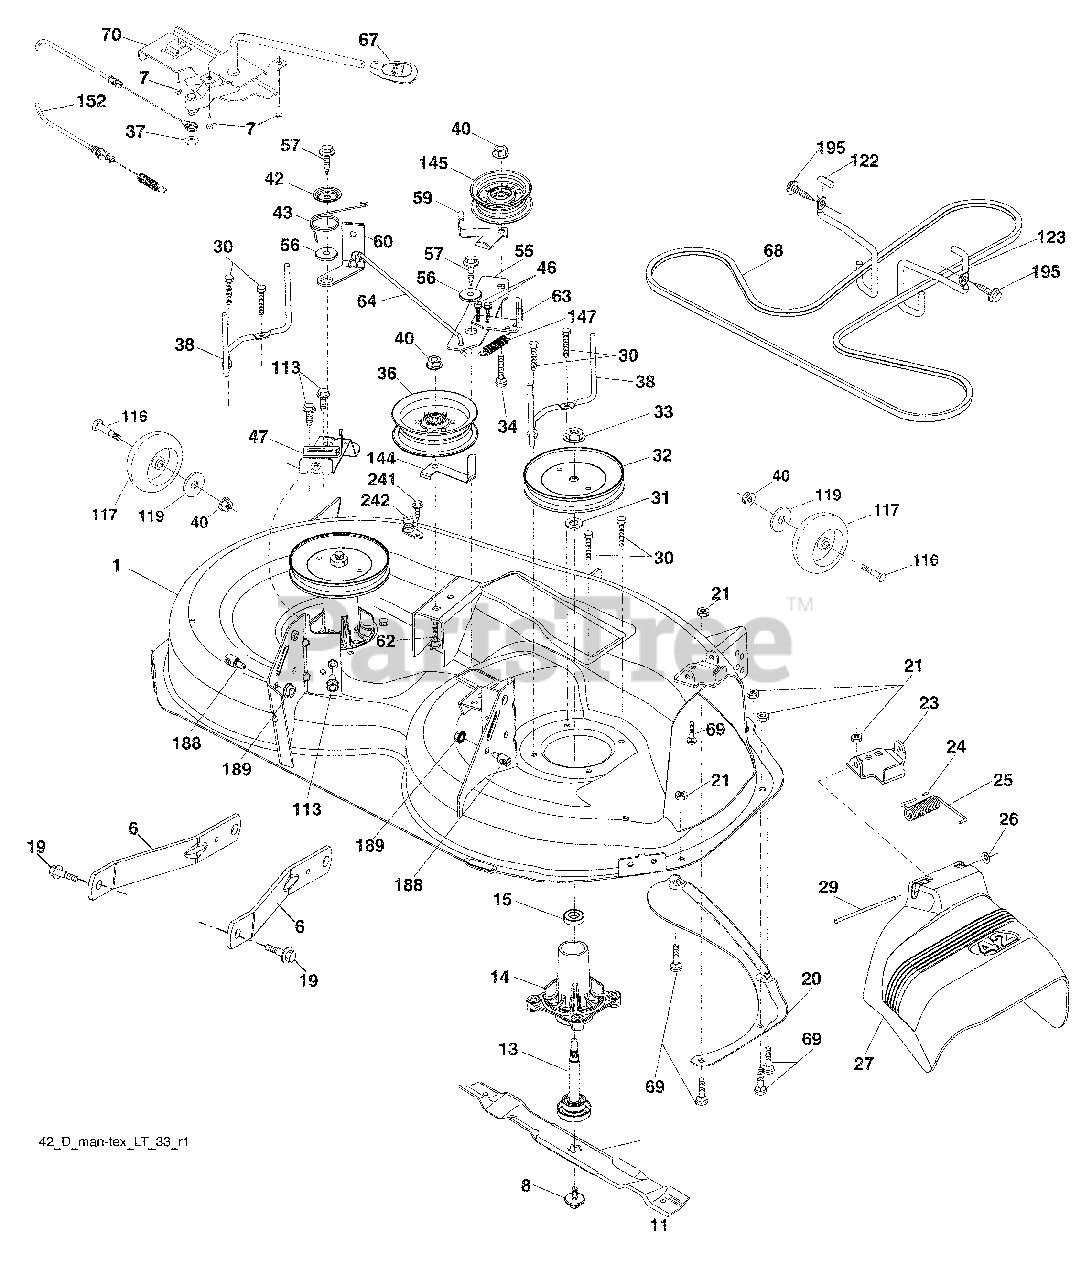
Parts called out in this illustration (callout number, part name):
1	Mower Housing
6	Arm Suspension
7	Screw #10 x 0.750 BOS Thread
8	Bolt/Washer Asm 7/16-20 unf
11	Blade High Lift
13	Shaft Assembly, Mandrel
14	Housing, Mandrel
15	Bearing, Ball, Mandrel
19	Bolt, Shoulder
20	Baffle Vortex
21	Nut
23	Bracket, Deflector
24	Cap, Sleeve
25	Spring, Torsion, Deflector
27	Shield, Deflector
29	Rod, Hinge
30	Screw Thdrol Rolling Wsh Hd
31	Washer, Spacer
32	Pulley, Mandrel
33	Nut, Toplock, Flanged
34	Bolt Carr Sh. 3/8-16 x1-1/2 Gr. 5
36	Pulley, Idler, Flat
37	Washer 13/32 x 13/16 x 16 Ja.
38	Keeper Belt LH Mandrel
40	Nut, Lock Flg. 3/8-16 unc
42	Spring Torsion Retainer
43	Spring Torsion Brake
46	Screw Thd Roll 1/4-20 x 5/8
47	Bracket Clutch Cable
55	Arm, Idler
56	Spacer, Retainer
57	Screw Hexwsh Thd 3/8-16 x 1
59	Guard, Tuv Idler (94)
60	Arm Brake Mower
62	Bolt 3/8-16 unc x 2
63	Arm Brake Mower
64	Linkage Brake
67	Handle Clutch Cable
68	V-Belt
69	Bolt
70	Clutch Asm Cable
113	Screw 5/16-18
116	Bolt, Shoulder
117	Wheel, Gauge
119	Washer 13/32 x 1-1/4 x 12 Ga.
122	Keeper Belt Engine LH
123	Keeper Belt Engine RH
144	Keeper Belt Mower
145	Pulley Idler
147	Spring Return
152	Cable Clutch CBL w/Spr
188	Stud Fastener
189	Nut Lock Hex Flange
192	Bracket Brake Stand LH
195	Screw Hexwsh Thdr 3/8-16 x 3/4
241	Screw TT #10-32.5.3/8 Flange
242	Washout Port
